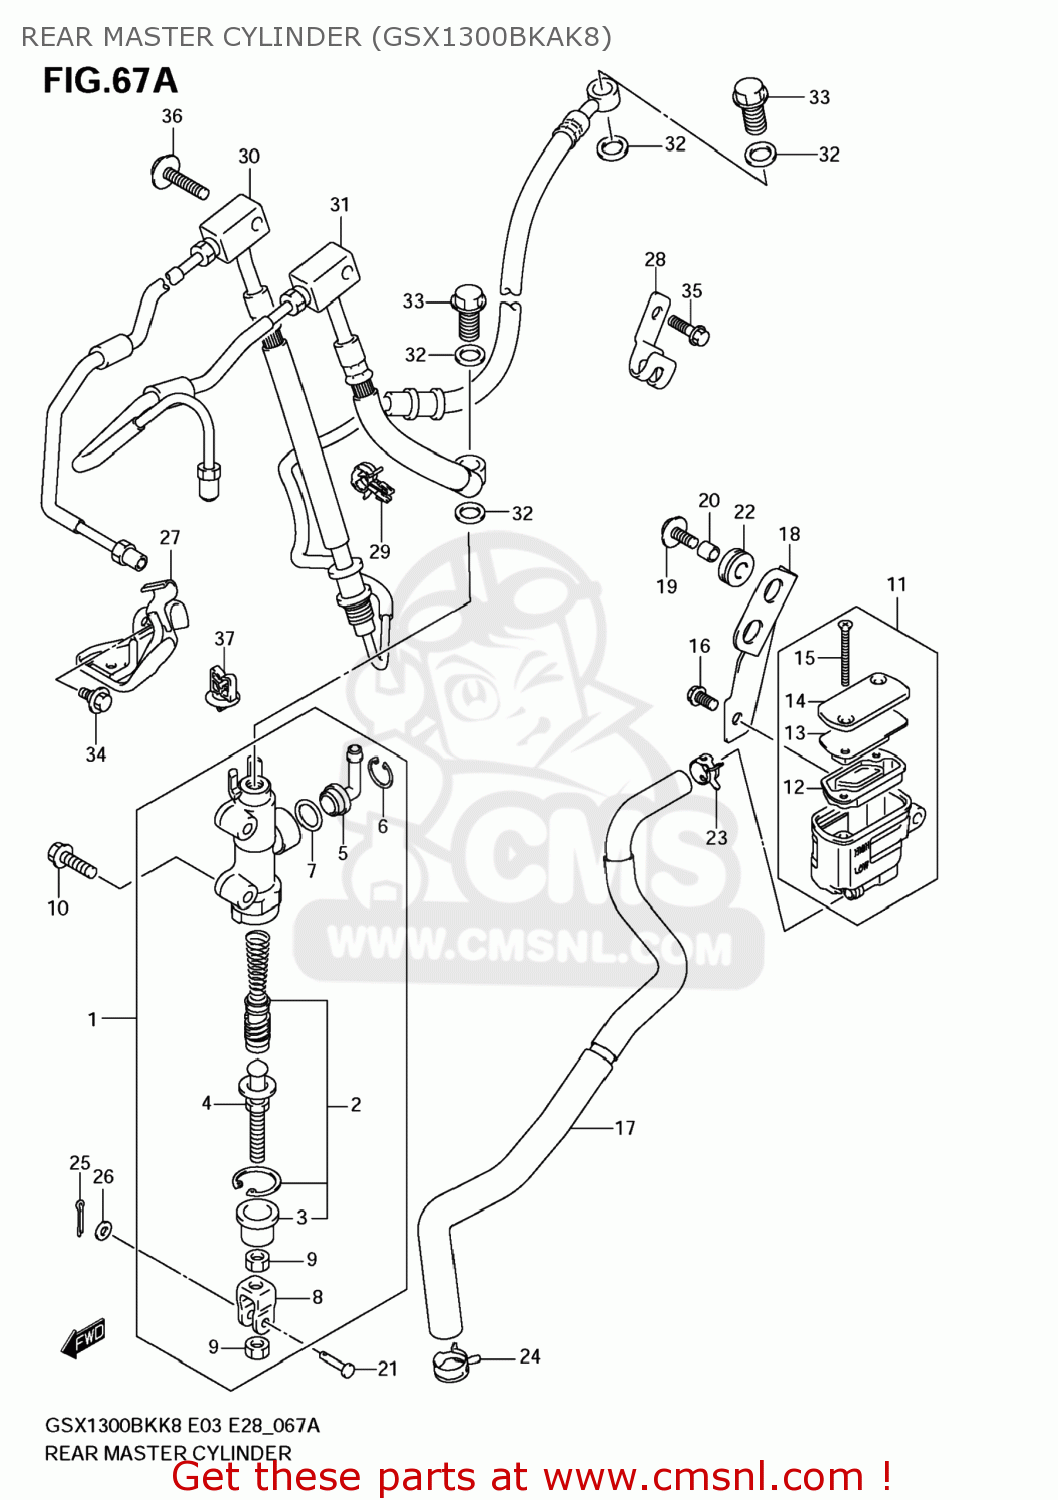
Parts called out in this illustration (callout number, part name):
1	CYLINDER ASSY,RR MASTER
2	PISTON/CUP SET
3	BOOT
4	ROD,PUSH
5	CONNECTOR
6	CIRCLIP
7	O RING
8	YOKE
9	NUT
10	SCREW(6X20)
11	TANK ASSY,RESERVOIR
12	DIAPHRAGM
13	PLATE,DIAPHRAGM
14	CAP
15	SCREW
16	BOLT
17	HOSE,RR RESERVOIR TANK
18	BRACKET,RR RESERVOIR TANK
19	BOLT(6X16)
20	SPACER(6.5X9X7.2)
21	PIN(6X18.2)
22	CUSHION
23	CLIP
24	CLIP
25	PIN
26	WASHER
27	CLAMP,RR BRAKE HOSE NO.2
28	CLAMP,RR BRAKE HOSE
29	CLAMP
30	HOSE ASSY,RR BRAKE NO.2
31	HOSE ASSY,RR BRAKE NO.1
32	WASHER(10X15X1.5)
33	BOLT UNION
34	BOLT(6X12)
35	BOLT
36	BOLT(6X35)
37	CLAMP,BK PIPE FRAME
